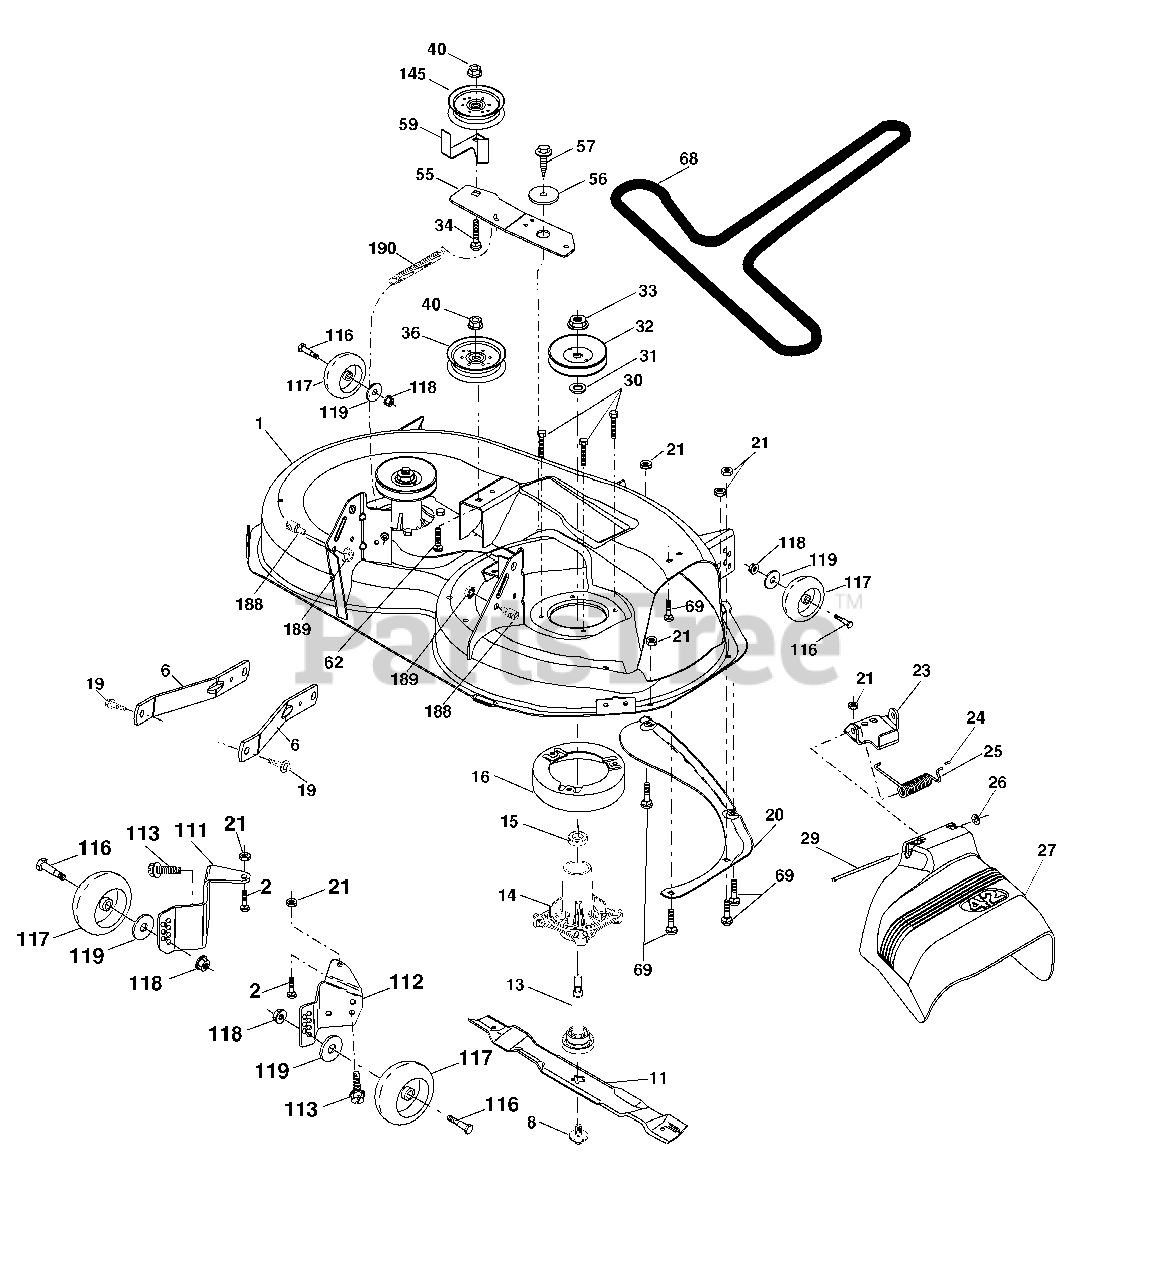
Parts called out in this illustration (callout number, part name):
1	Mower Deck Assembly, 42"
2	Bolt Rdhd Sqnk 5/16-18 unc x 3/4
6	Arm Susp. Rear
8	Bolt/Washer Asm 7/16-20 unf
11	Blade Mower 42" Hi-Lift
11	Blade, Mulching 42" Std
11	Blade Mulching 42" Premium
13	Shaft As sem bly, Mandrel
14	Housing, Mandrel
15	Bearing, Ball, Mandrel
16	Stripper, Mandrel Deck
19	Bolt, Shoulder
20	Baffle, Vortex
21	Nut
23	Bracket, Deflector Mower 42"
24	Cap, Sleeve 80 x 112 Blk Mower
25	Spring, Torsion, Deflector
26	Nut, Push Phos & Oil
27	Shield, Deflector 42" Blk
29	Rod, Hinge 42" 6 75 W/G
30	Screw Thdrol
31	Washer, Spacer Mower Vented
32	Pulley, Mandrel
33	Nut, Toplock
34	Bolt Carr SH 3/8-16 x 1-1/2 Gr. 5
36	Pulley, Idler, 4.50 RAW
40	Nut Lock 3/8-16
55	Arm, Idler
56	Spacer, Retainer
57	Screw 3/8-16 x 1
59	Guard TUV Idler
62	Bolt Rdhd Sqnk 3/8-16 unc x 2
68	V-Belt, 42" Mower
69	Bolt, Carriage 5/16-18 x 5/8
111	Bracket Wh Gauge LH
112	Bracket Wh Gauge RH
113	Screw 5/16-18
116	Bolt, Shoulder
117	Wheel, Gauge
118	Nut Centerlock 3/8-16
119	Washer 3/8 x 7/8 x 14
145	Pulley Idler Primary
188	Stud Fastner W/D Anti-Rotation
189	Nut Lock Hex Flange 5/16-18
190	Spring Mower Drive
190	Mandrel Assembly
190	Replacement Mower, Complete
